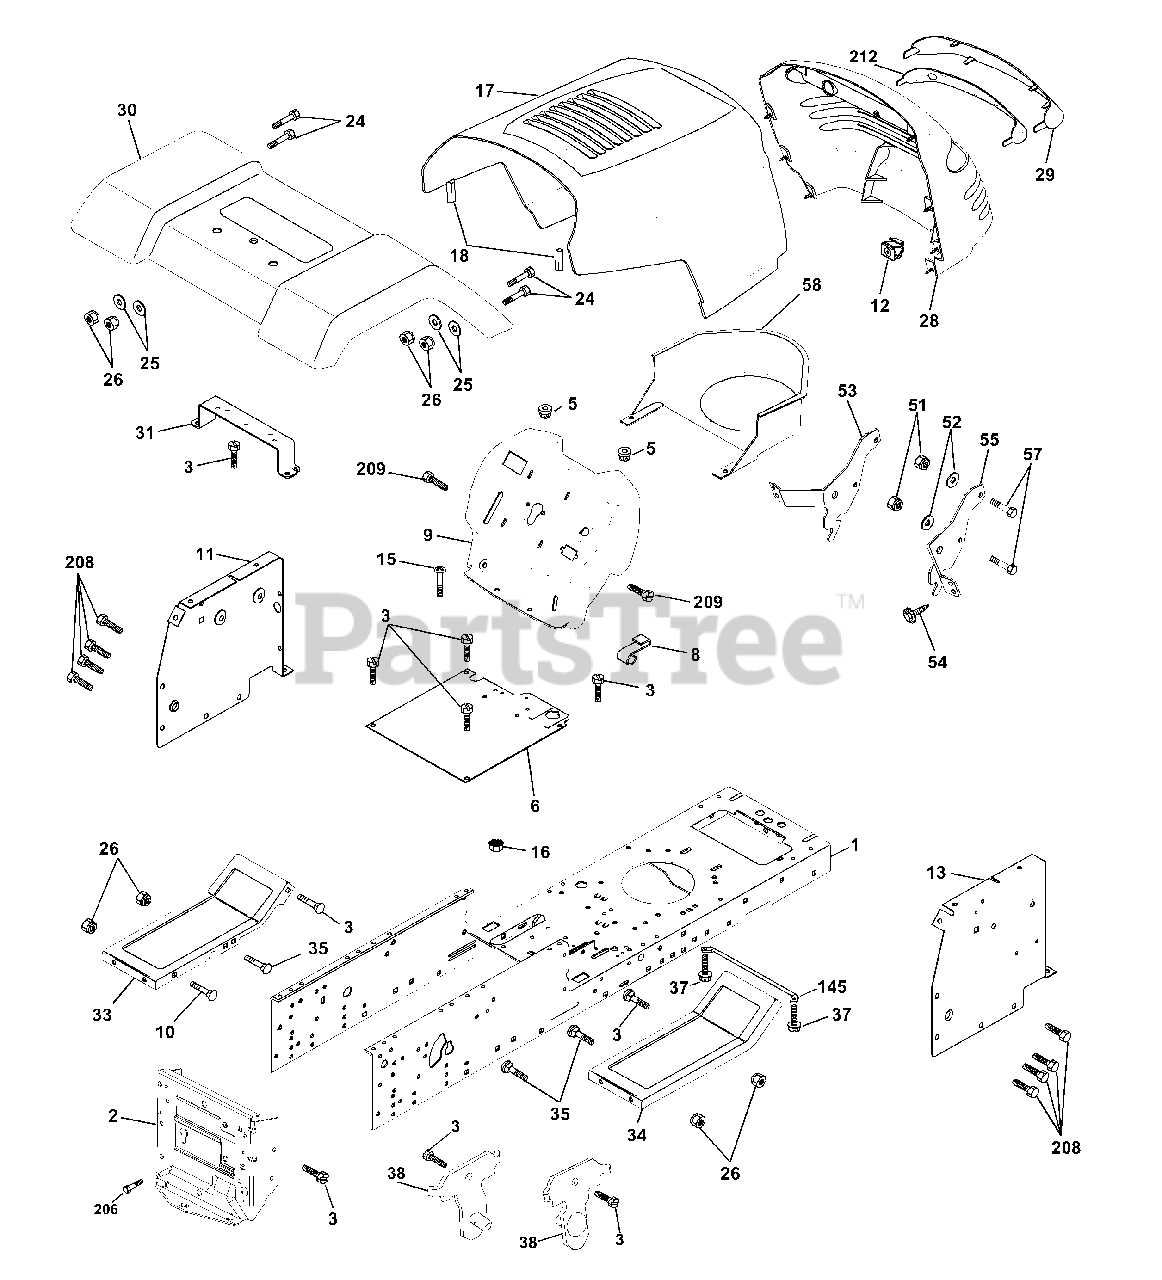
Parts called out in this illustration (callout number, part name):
2	Drawbar
3	Screw 3/8-16 x 3/4
5	Bumper Hood/Dash
6	Saddle Slkscr Flat Lt 6Sp
8	Clip Retainer Slide-On
9	Dash
10	Bolt Rd Hd Sqnk. 3/8-16 Unc x 1
11	Panel Asm. Dash Lh
12	Clip Tinnerman Grile P/L
15	Screw Mach Trhd 5/16-18 Unc x 3/4
16	Nut Keps 5/16-18 Unc
17	Hood
18	Bumper Hood
24	Bolt Fin Hex 3/8-16 Unc x 1 Gr. 5
25	Washer 13/32 x 13/16 x 12 Ga.
26	Nut Lock Hex w/Insert 3/8-16 UNC
28	Grill/Lens Asm
29	Lens Grille Private label
30	Fender Asm
31	Bracket Fender
33	Footrest Lh
34	Footrest Rh
35	Bolt Rd Hd Sht. Sqnk. 3/8-16 x 3/4
37	Screw Thdrol 5/16-18 x 1/2 Tyt
38	Bracket Asm. Pivot Mower Rear
51	Nut Lock Hex W/Ins. 1/4-20
52	Washer 9/32 x 7/8 x 16 Ga.
53	Bracket Grille LH
54	Screw Hex Wshd 8-18 x 7/8
55	Bracket, Grille RH
57	Bolt Fin Hex 1/4-20 x .75
58	Air Duct Private Label
145	Rod Pivot Chassis/Hood
206	Bolt shoulder 5/16-18
208	Screw Thdrol 3/8-16 x 1/2
209	Screw Hex Wsh Thdrol 3/8-16
212	Insert Lens Reflector
